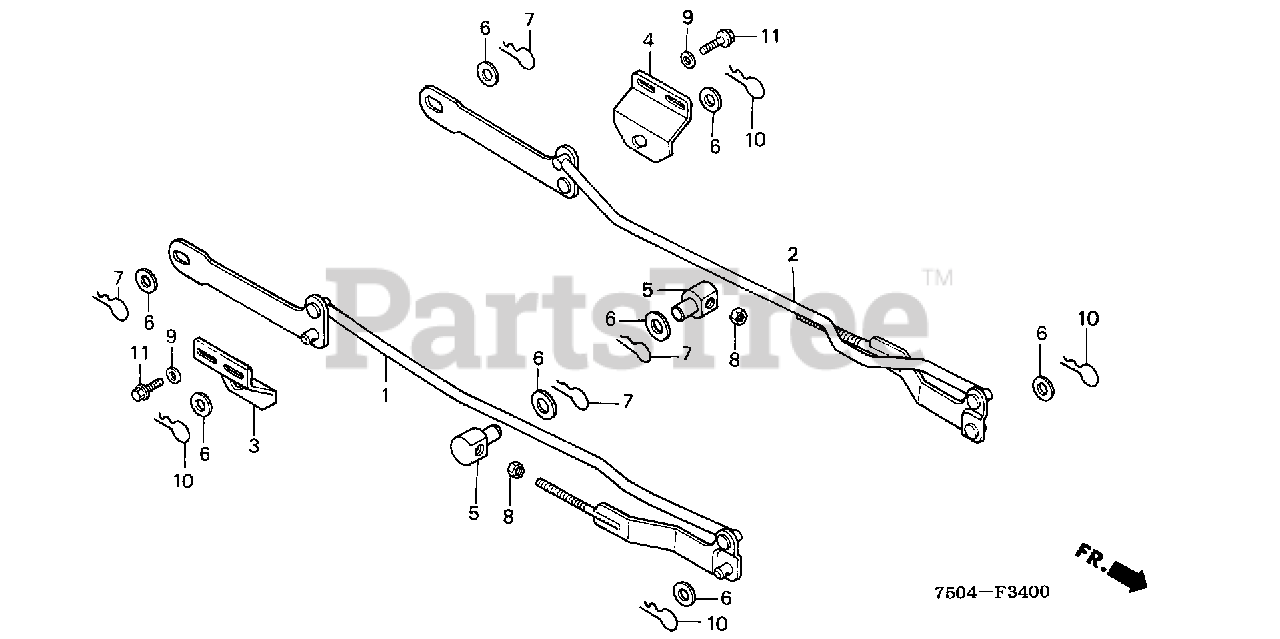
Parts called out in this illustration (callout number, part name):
1	LINK, R. CUTTER DECK
2	LINK, L. CUTTER DECK
3	BRACKET, R. RR. LINK
4	BRACKET, L. RR. LINK
5	PIN, FR. LINK ADJUSTING
5	PIN, FR. LINK ADJUSTING (NOT AVAILABLE)
6	WASHER, PLAIN (14MM)
7	PIN, LOCK (2.3MM)
7	PIN, LOCK (14MM)
8	NUT, HEX. (12MM)
9	WASHER, PLAIN (8MM)
10	PIN, LOCK (14MM)
11	BOLT, FLANGE (8X18)
